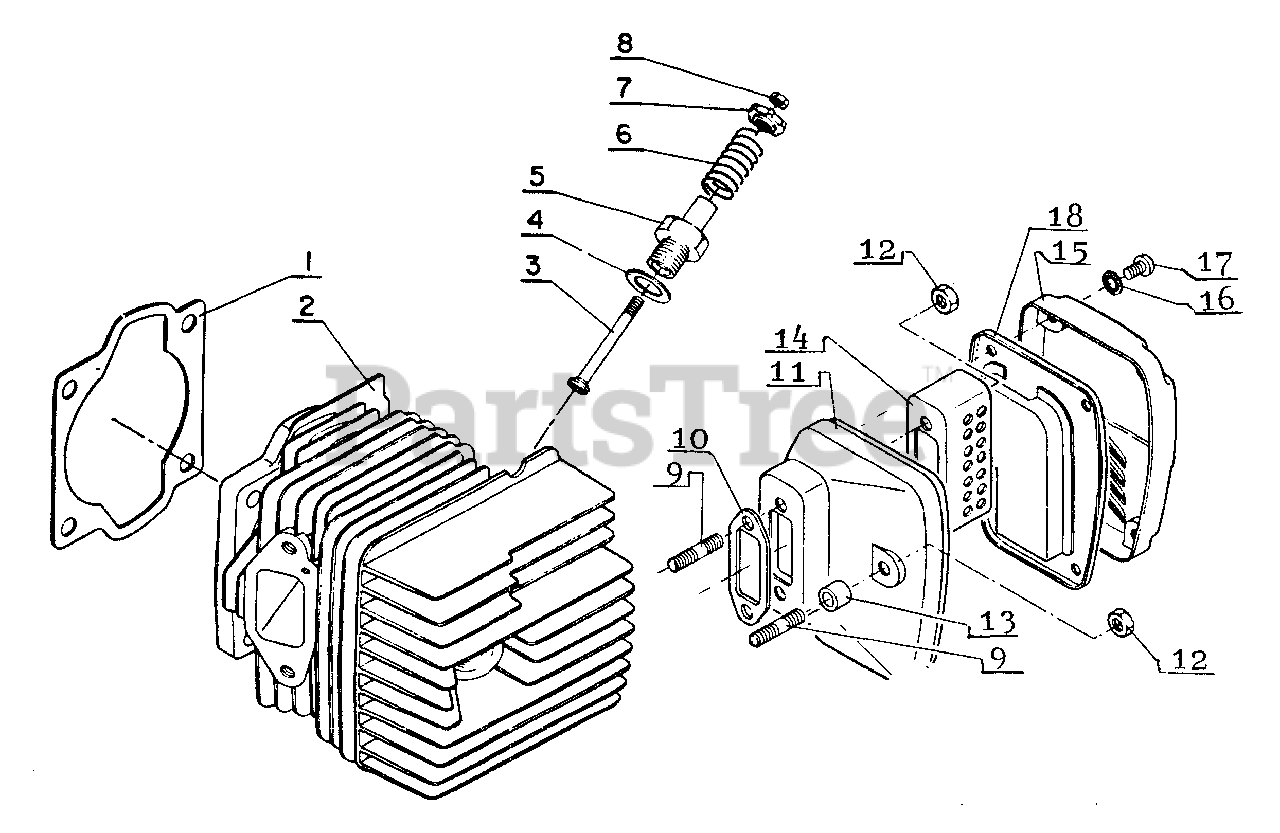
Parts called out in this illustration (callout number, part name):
1	GASKET, CYLINDER
2	CYLINDER
3	VALVE, DECOMPRESSION
5	SEAT, VALVE
6	SPRING, VALVE
10	GASKET, EXHAUST
11	MUFFLER
12	LOCKNUT - 6
14	BAFFLE, MUFFLER
15	LID, MUFFLER
16	LOCKWASHER - 5
17	SCREW - 5X8
18	PLATE
